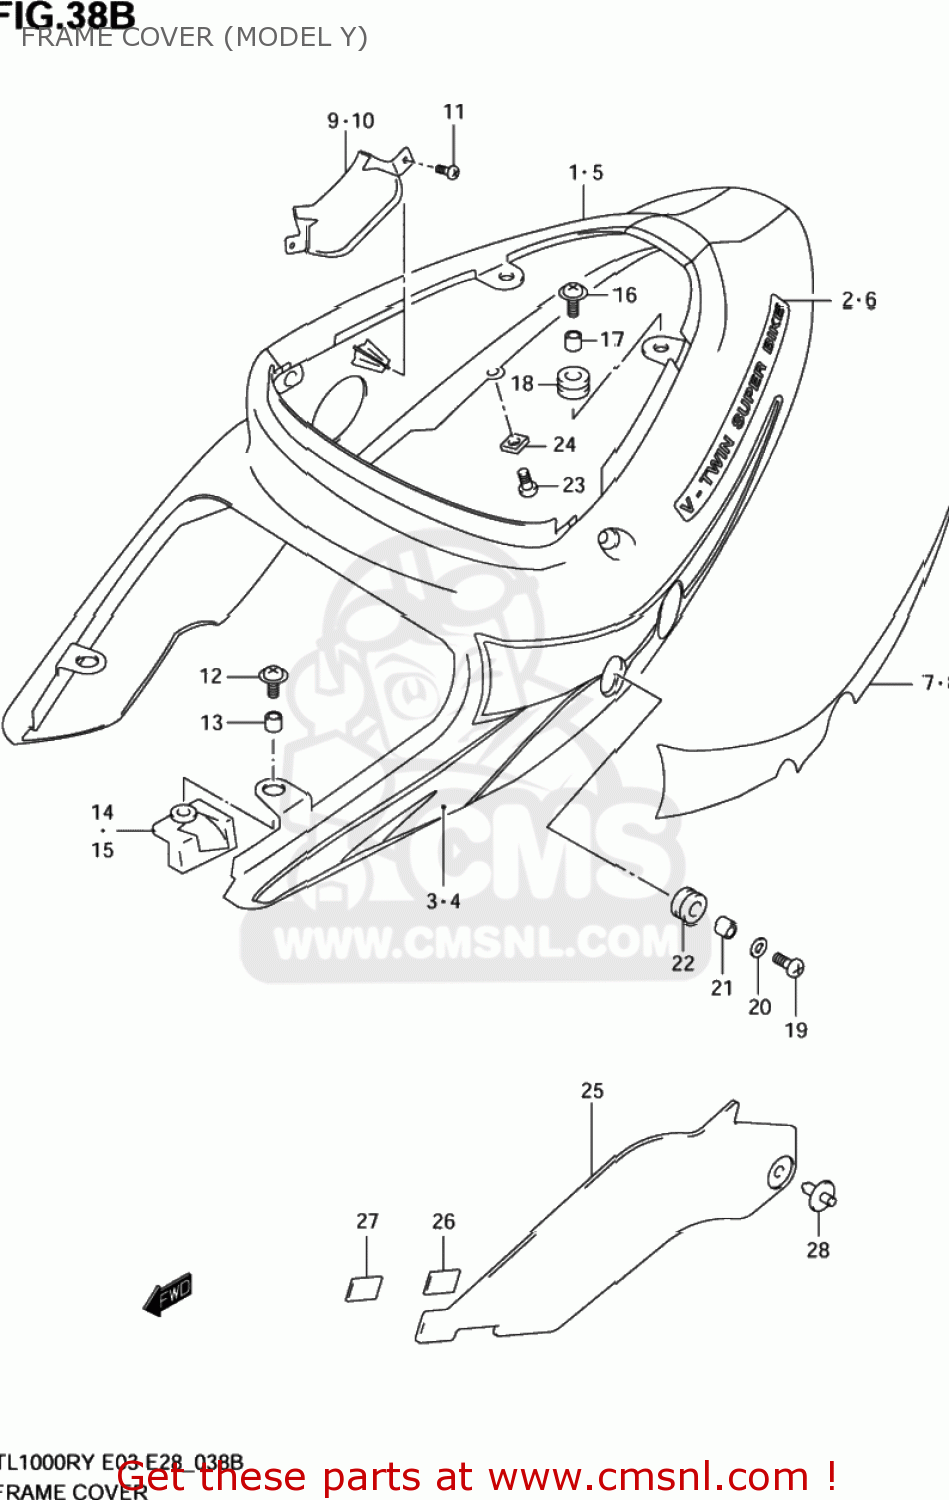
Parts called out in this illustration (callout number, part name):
1	COVER,FRAME
2	EMBLEM,FRAME COVER
3	TAPE,FRAME COVER,R
4	TAPE,FRAME COVER,L
5	COVER COMP,FRAME
6	EMBLEM,FRAME COVER
7	TAPE,FRAME COVER,R
8	TAPE,FRAME COVER,L
9	CAP,FRAME COVER HOLE,R
10	CAP,FRAME COVER HOLE,L
11	SCREW
12	SCREW(6X20)
13	SPACER(6.5X9X9)
14	CUSHION,FRAME COVER,R
15	CUSHION,FRAME COVER,L
16	SCREW(6X20)
17	SPACER(6.5X10X9.4)
18	CUSHION
19	SCREW(6X20)
20	WASHER(6.5X22X1.6)
21	SPACER(6.5X9X6.7)
22	CUSHION
23	CLIP
24	NUT
25	COVER,FRAME,FRONT,RIGHT
26	FASTENER,NO.1
27	FASTENER,NO.2
28	CLIP(GRAY)
